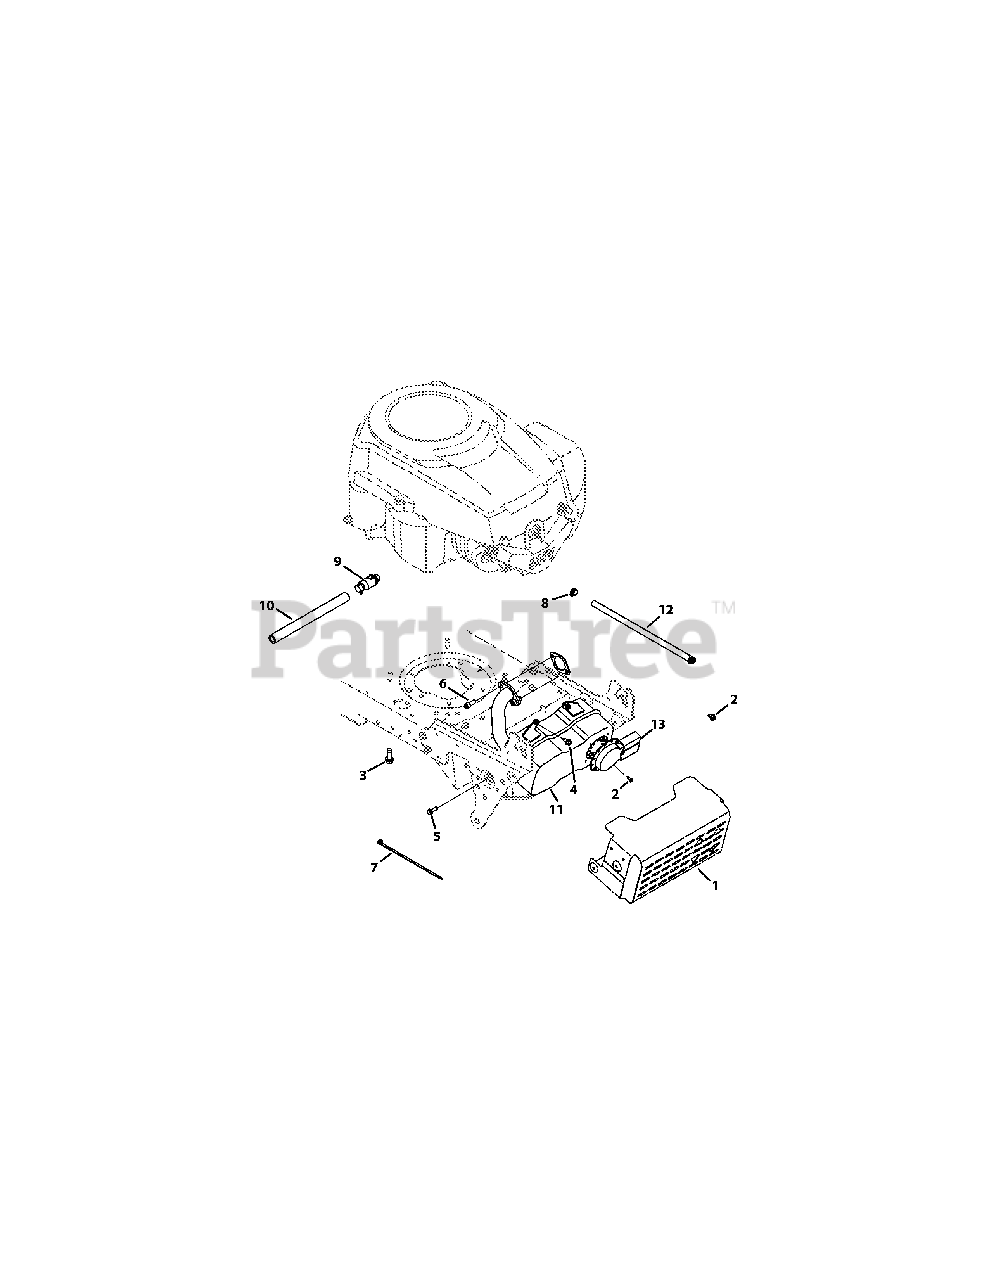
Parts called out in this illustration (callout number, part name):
1	Muffler Shield Assembly with Weld
2	Screw, 8-18 x .500
3	Screw, 3/8-16 x 1.0
4	Screw, 1/4-20 x .500
5	Screw, 1/4-20 x .750
6	Socket Screw, 5/16-18 x .750
7	Cable Tie
8	Clamp Hose, .490 diameter
10	Oil Drain, Extension Hose
11	Muffler
12	Fuel Hose, Low Permeation
13	Muffler Deflector Long
